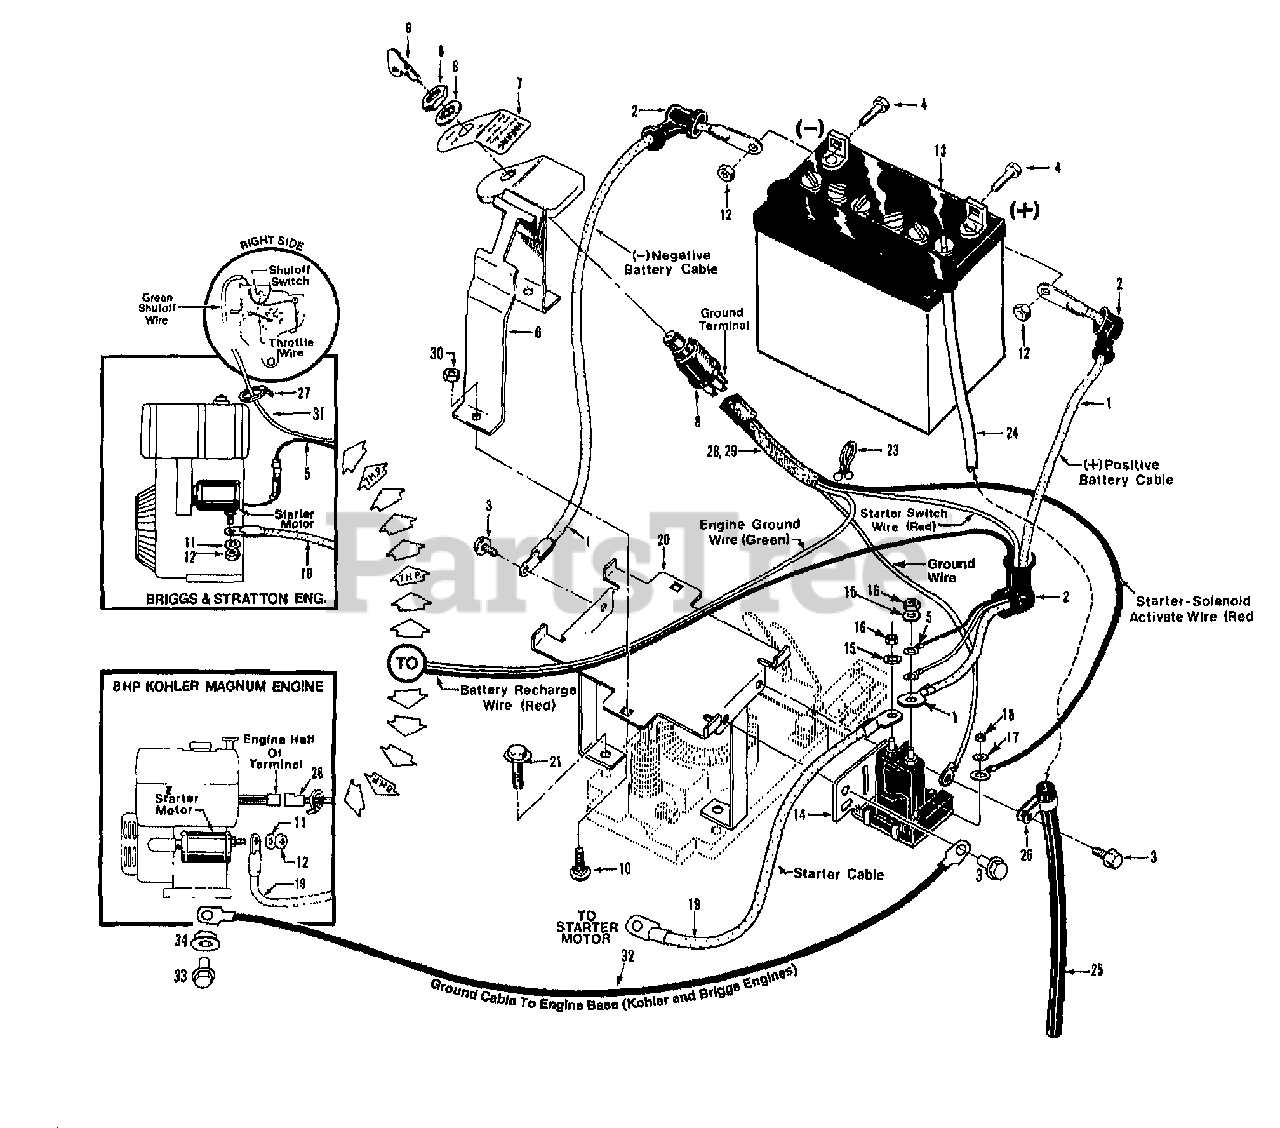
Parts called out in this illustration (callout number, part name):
1	CABLE-BATTERY 10"
2	BOOT-BATTERY CABLE
3	SCR-HWH 1/4-20 X .5 STH
4	SCR-HH 1/4-20X.625
5	WIRE-RECHARGE 5&7 BRIGGS
6	KEYSWITCH W/DECAL HORSE
7	DECAL-IGNITION TILLERS
8	ASSM-KEYSWITCH ELEC TLR
9	KEYS-IGN T/BLAZER 1 PAIR
10	SCR-CARR 1/4-20X1.25
11	WASHER-LK .25 ZP
12	NUT-HEX 1/4-20 ZP
13	BATTERY-12 VOLT HORSE
14	SOLENOID
15	WASHER-LK .312 ZP
16	NUT-HEX 5/16-24
17	WASHER-EXTERNAL TOOTH 1
18	NUT-HH M10-32X.125
19	CABLE-BATTERY 12"
20	BRKT-BATTERY OPC PNT
21	SCR-HFLK 3/8-16X1.50
23	TIE-TWIST LOCK
24	TUBE-VENT BATTERY/HSE
25	TUBING-RUBBER
26	CLAMP
27	TIE-RED
28	KIT-WIRE HARNESS ASSM
29	ASSM-WIRE HARNESS
30	NUT-HF/LK 1/4-20 ZP
31	ASSM-WIRE SWITCH/GROUND
31	CABLE-BATTERY 15"
32	CABLE-BATTERY 15"
33	SCR-HFLK 5/16-18X1.00 ZP
34	NUT-HFLK 5/16-18 ZP
